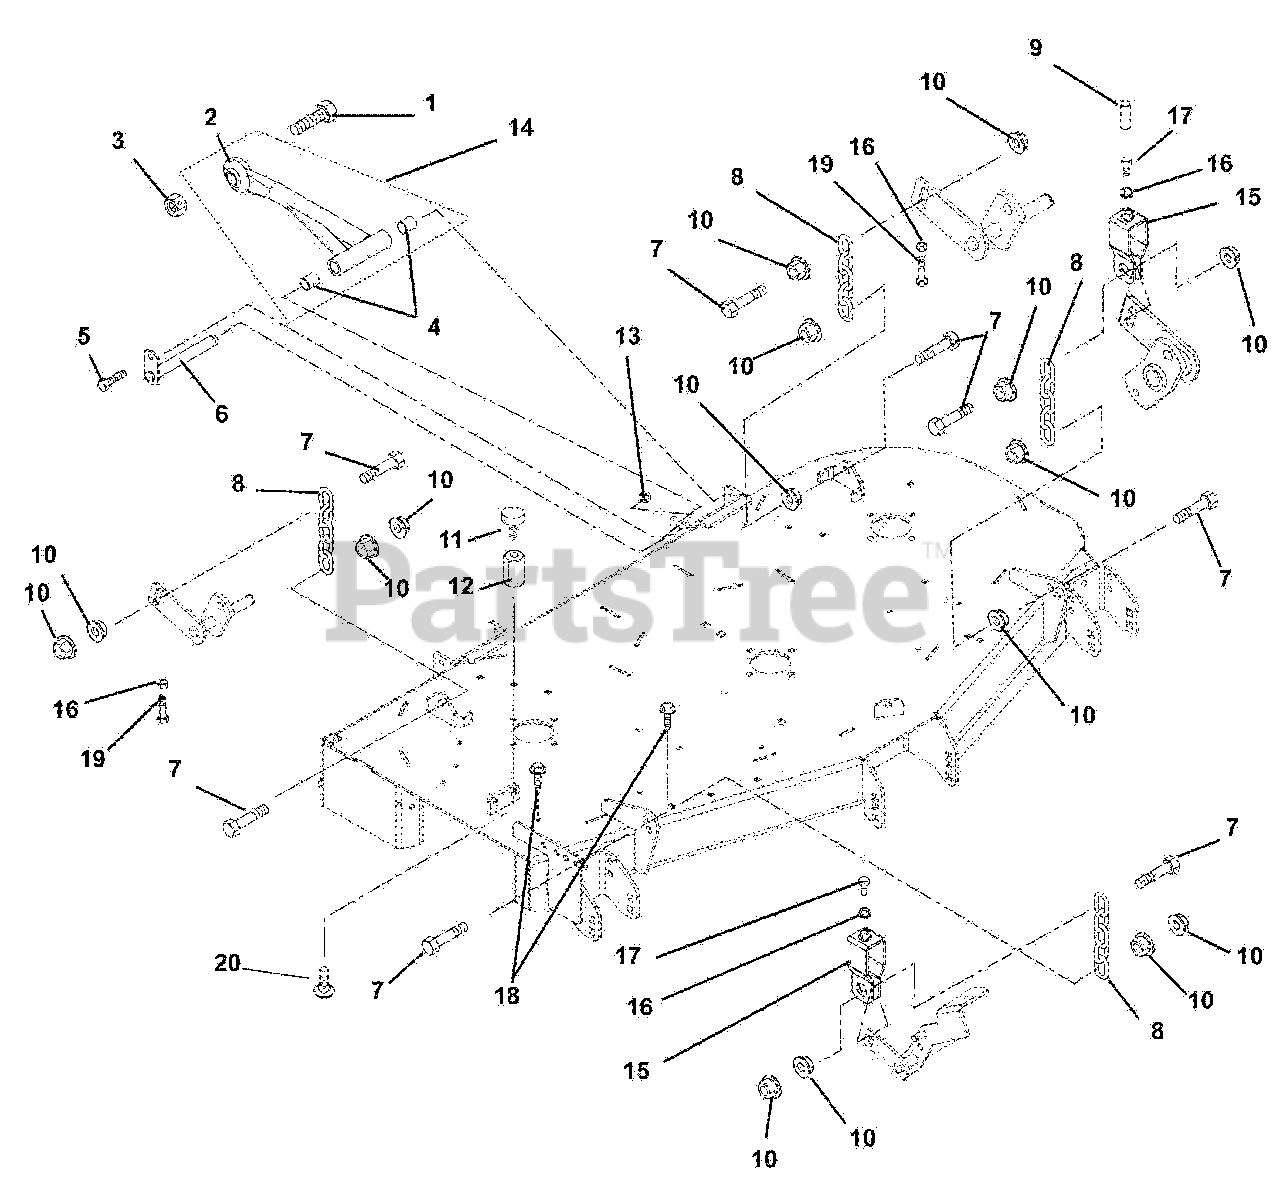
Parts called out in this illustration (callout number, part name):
1	Bolt, Hex .875-9 x 2.75 Grade 5
2	Mower Mounting Arm Weldment
3	Nut, Locking-Center .875-9
4	Bearing, .75 x .875 x 1.00
5	Bolt, Hex .38-16 x .75 Grade 5
6	Weldment, Mower Mounting Pin
7	Bolt, Hex M12-1.75 x 50 Grade 5
8	Chain, Link
9	Cap, Vinyl .50ID x 1.50LG x .055
10	Nut, Spin Lock-Flange M12-1.75
11	Bumper, Rubber
12	Coupling Nut, .31-18 x 3.00
13	Nut, .38-16 Nyloc Flange
14	Assembly, Mower Mounting Arm (Includes item # 2 and item # 4)
15	Bracket, Deck Leveling
16	Nut-Jam .312-18
17	Bolt, Hex .31-18 x 2.00 Full Thread
18	Screw, Tapping .38-16 x .50 Hex Washer Head Thread (992156)
19	Bolt, Hex .312-18 x 1.50 Grade 5
20	Bolt, Round Head Square Neck .31-18 x .75 Loc-Tite
